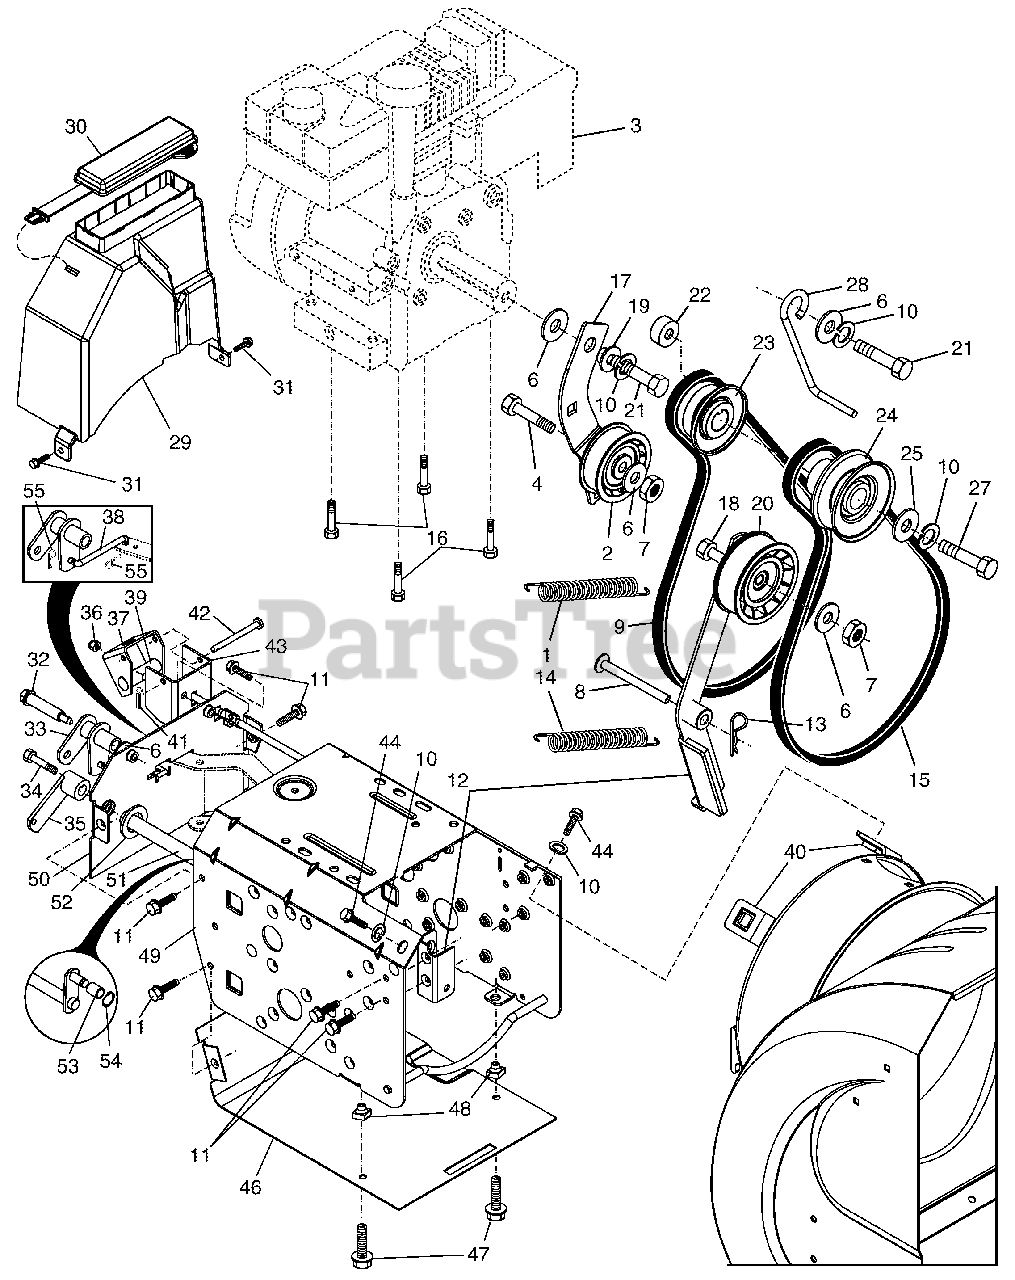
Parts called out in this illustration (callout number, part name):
1	Spring, Traction Idler
2	Pulley, Idler (2-1/4)
4	Screw, Hex Head 5/16-18 x 1-1/4
6	Washer, Flat
7	Nut, Jam, Lock 5/16-18
8	Pin, Idler Pivot
9	V-Belt, Traction Drive
10	Washer, Lock 5/16
11	Screw, Hex Head 5/16-18 x 3/4
12	Impeller Idler Arm & Bracket Assembly
13	Retainer, Hairpin
14	Spring, Brake
15	V-Belt, Impeller Drive
16	Screw, Hex Head 3/8-16 x 1-1/4
17	Arm, Idler
18	Screw, Hex Head 5/16-18 x 1-1/2
19	Bushing, Idler Pivot
20	Pulley, Idler (2-3/4)
21	Screw, Hex Head 5/16-18 x 1
22	Spacer, Engine Pulley
23	Pulley, Engine, Traction Drive
24	Pulley, Engine, Impeller Drive
25	Washer, Flat 3/8
27	Screw, Hex Head 3/8-24 x 1-3/8
28	Guide, Belt
29	Cover, Belt
30	Cover, Toolbox
31	Screw, Hex Head 1/4-20 x 1/2
32	Bolt, Shoulder 5/16-18
33	Bellcrank Shifter
34	Screw, Hex Head 1/4-28 x 3/4
35	Arm, Auger Control
36	Nut, Lock 5/16-18
37	Bellcrank Assembly
38	Link, Speed Control
39	Trunnion, Pivot Bracket
40	Nut, Cage 3/8-16
41	Pin, Cotter 1/16 x 1/2
42	Pin, Pivot Bracket
43	Bracket, Bellcrank
44	Screw, Hex Head 3/8-16 x 1-1/2
46	Pan, Frame Bottom
47	Screw, Hex Head 5/16-18 x 3/4
48	Nut, Speed 5/16-18
49	Frame Assembly
50	Plate, Frame End
51	Shaft, Auger Control
52	Washer, Hardened
53	Roller
54	Ring, Retaining
55	Clip, Retainer
